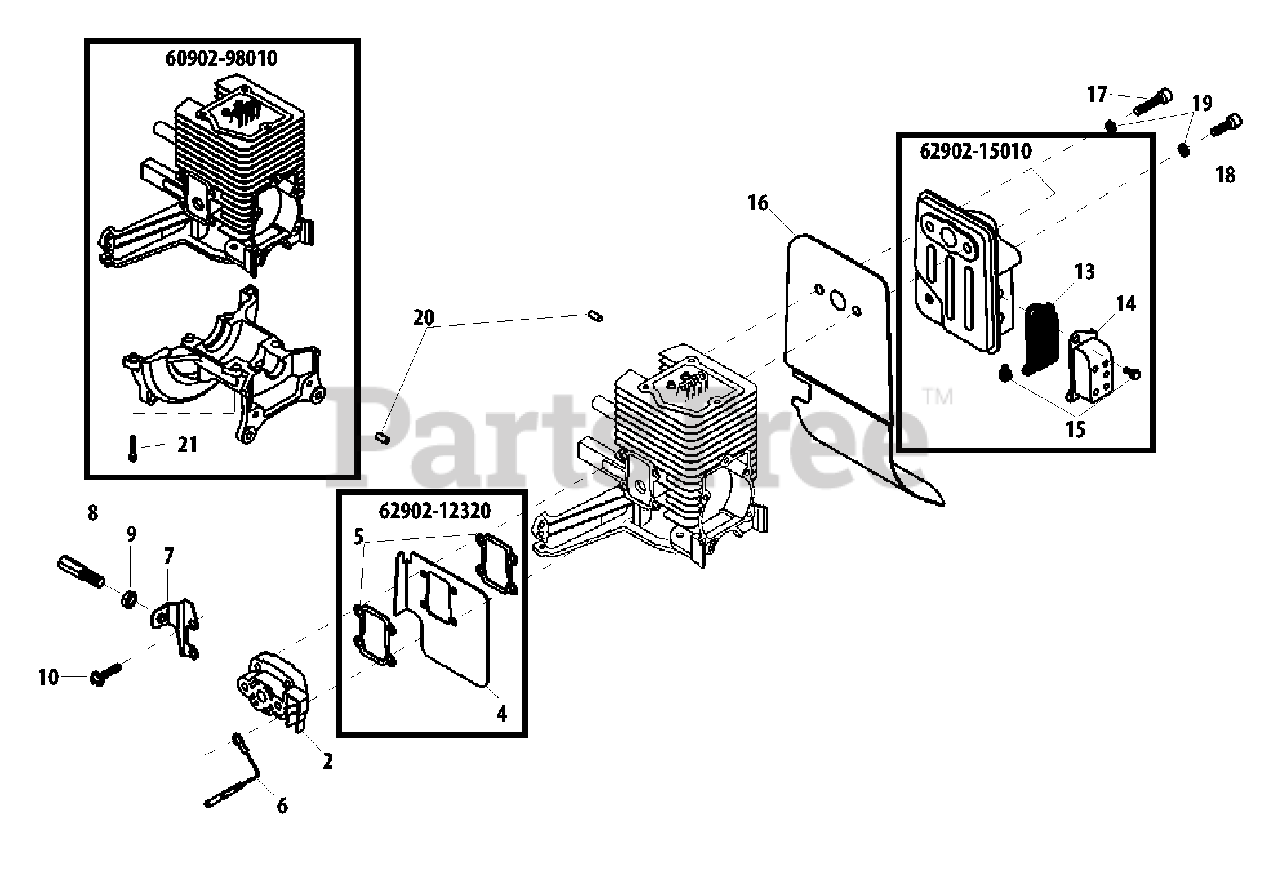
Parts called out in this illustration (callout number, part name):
2	INSULATOR
4	DEFLECTOR, HEAT
5	SHIELD, INTAKE
6	LEAD - GROUND
7	BRACKET, THROTTLE CABLE
8	NUT, CABLE ADJUST
9	LOCKNUT - 6
10	SCREW - 5X22
13	SCREEN, SPARK ARRESTOR
14	GUIDE, EXHAUST
15	SCREW - 4X6
16	SHIELD, EXHAUST
17	SCREW - 5X25
18	SCREW - 5X16
19	WASHER - 5
20	PIN - LOCATING
21	SCREW - 5X16
60902-98010	CYLINDER BLOCK SET
62902-12320	HEAT DEFLECTOR ASSY
62902-15010	MUFFLER ASSY
